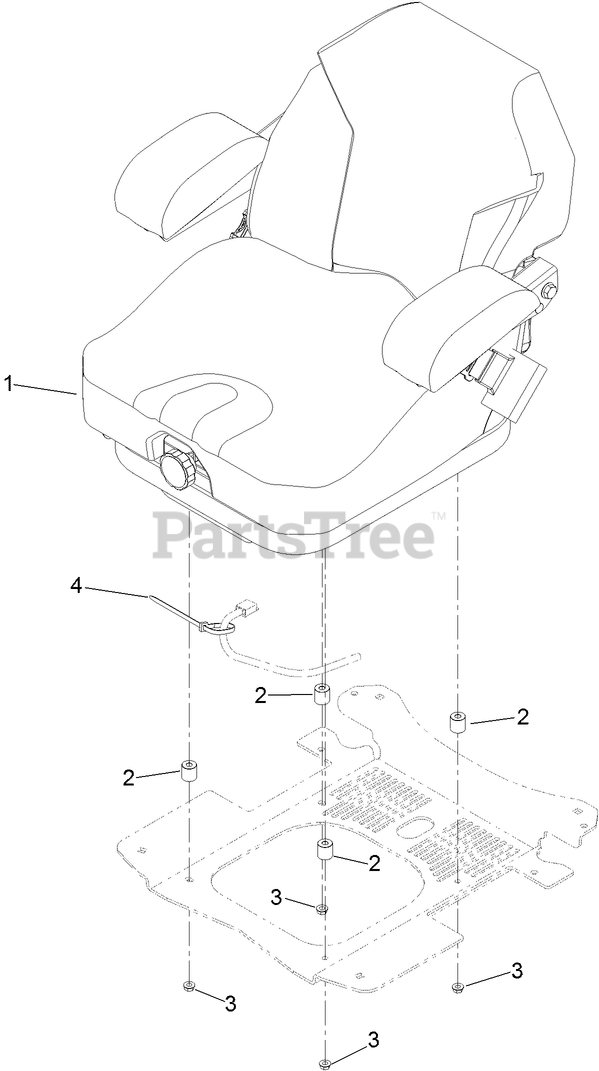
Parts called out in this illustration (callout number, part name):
1	SUSPENSION SEAT ASM
2	SPACER
3	NUT-HF
4	TIE-PLASTIC
